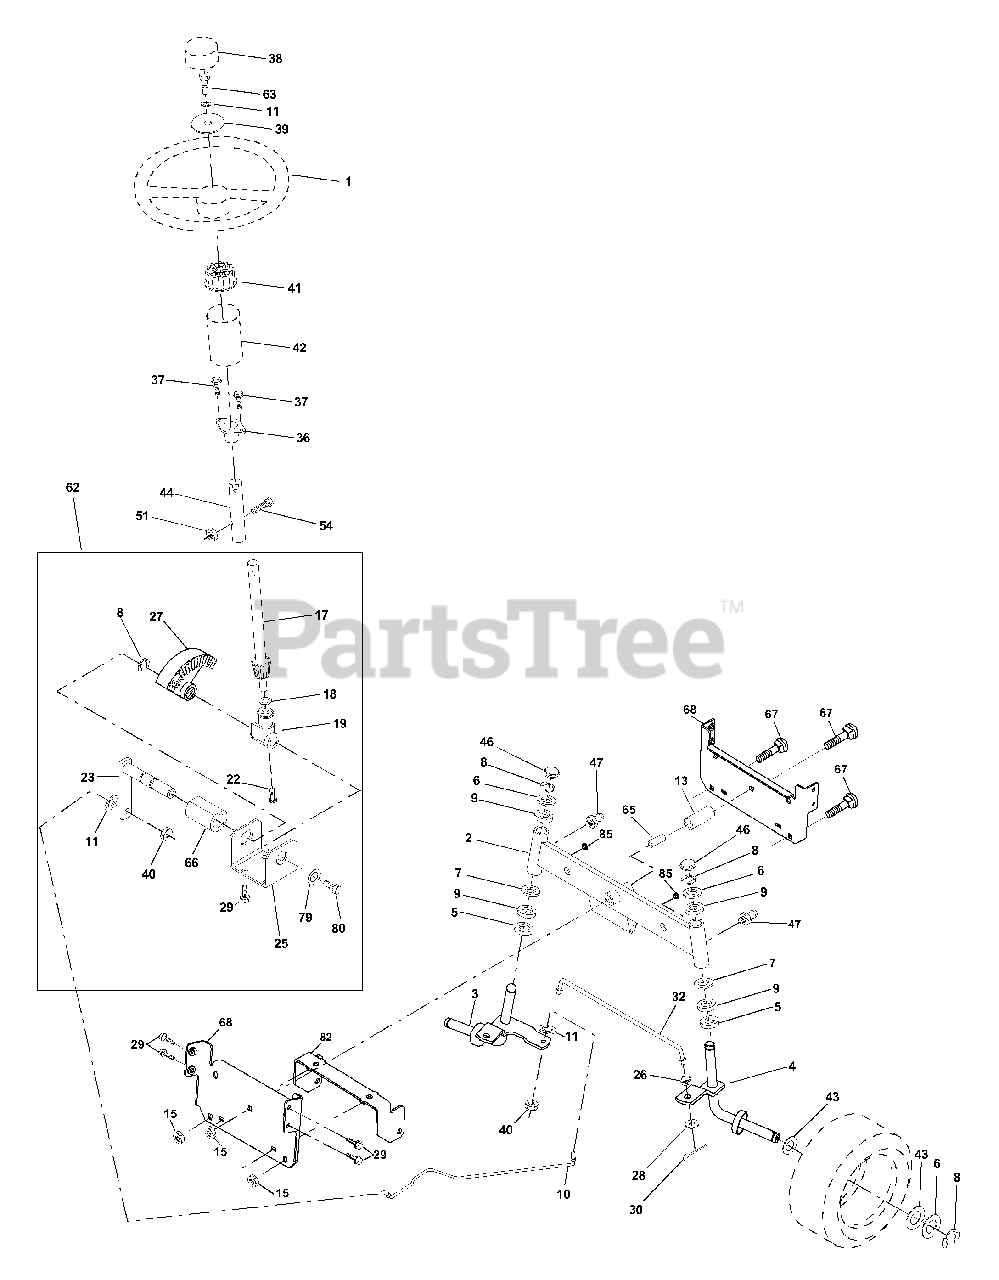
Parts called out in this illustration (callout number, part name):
1	Wheel Steering Auto Black
2	Axle Asm Front
3	Spindle Asm Lh
4	Spindle Asm Rh
5	Bearing Race Thrust Harden
6	Washer 25/32 X 1 5/8 X 16ga
7	Washer 27/32 X 1 1/4 X 16 Ga
8	Ring Klip #t5304-75
9	Bearing Col Strg Blk
10	Link Drag Extended
11	Lockwasher
13	Spacer Bearing Axle Front
15	Hex Flange Lock
17	Shaft Asm Strg 5/8 X 15 19 Lt
18	Washer Thrust 515x 750x 033
19	Support Shaft
22	Screw Hex Wsh Hd Torx
23	Shaft Asm Pittman
25	Bracket Steering
26	Bushing Rod Tie Blk Lt
27	Gear Sector
28	Washer 13/32 X 7/8 X 16ga
29	Screw 3/8-16x3/4
30	Pin
32	Rod Tie Wire Form 19 75 Mech
36	Bushing Strg 5/8 Id Dash
37	Screw TT #10-32 x 5 x 3/8 Flange
38	Insert Cap Strg
39	Washer 13/32 x 2-3/8 x 12Ga
40	Locknut Center
41	Adaptor Wheel Strg 640/ 635id
42	Boot Dash Steering
43	Washer 25/32 X 1 1/4 X 16 Ga
44	Extension Steering Non-Adjust
46	Cap Spindle Fr Top Blk
47	Fitting Grease
51	Nut Lock Hex W/Ins.
54	Bolt Fin Hex 5/16-18 Unc P
62	Kit Steering Assembly Service
63	Bolt Fin Hex 3/8-16unc x Gr. 5
65	Spacer Brace Axle
66	Bearing Arm Pittman
67	Bolt Rdhd Sq 3/8-16 Unc x 2-3/4
68	Brace Axle
79	Washer 13/32 x 1-1/4 x 12 Ga
80	Bolt Hex Nylon 3/8-16 x 3/4
82	Bracket Susp Chassis Front
85	Fastener Christmas Tree
